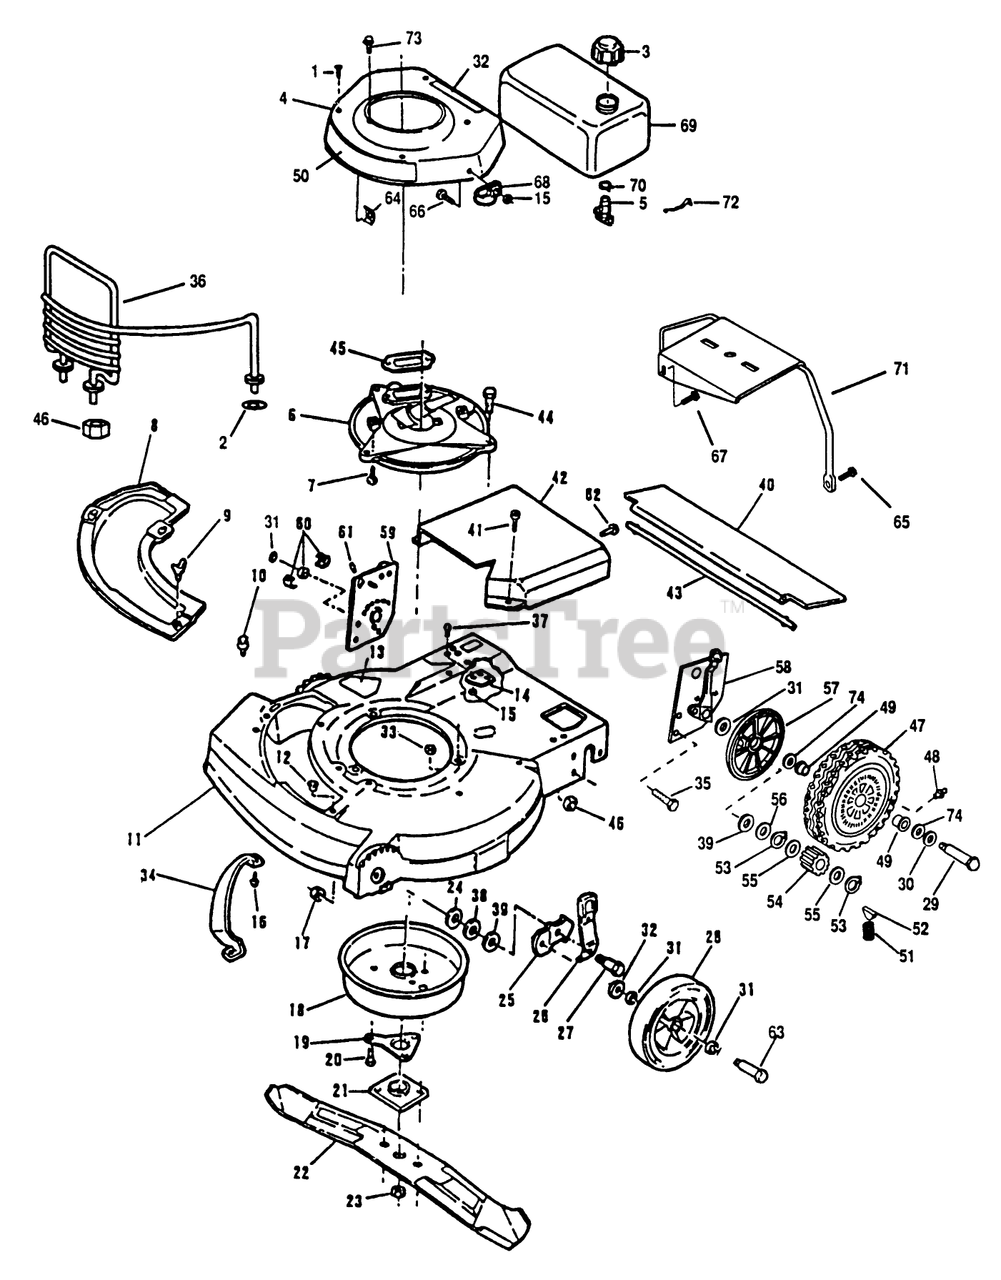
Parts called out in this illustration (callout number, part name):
1	SCREW - SELF TAPPING
3	FUEL CAP & INSERT
5	VALVE&SCREEN SM
6	PLATE F
7	SCREW V
9	WING SCREW LAWRE
14	BOLSTER
15	LOCKNUT E
18	MUFFLER COVER F
19	SUPPORT F
21	PLATE AND COLLAR ASM
23	NUT-BLADE
26	SPRING ARM ASM
28	WHEEL AND TIRE ASM
29	BOLT WHEEL
33	NUT-LOCK F
34	BAR-TOE
36	SCREW S
40	SHIELD-TRAILING
41	SCREW SEMS TRM HEX HD
44	SCREW-HH
46	NUT-LOCK F
48	FITTING LINCOLN
53	RET RING
54	PINION BROCKWAY
55	SPACER/GR ALGHNY
56	THRUST WASHER
57	COVER-WHEEL
59	HEIGHT ADJ AY-RH
60	REAR AXLE BEARING
61	**FITTING LINCOLN
63	BOLT-SHOULDER
64	PUSHNUT F
70	CLAMP - HOSE S
71	BRACKET AY-TANK *B
73	SCREW SEMS SM
74	WASHER-FELT
